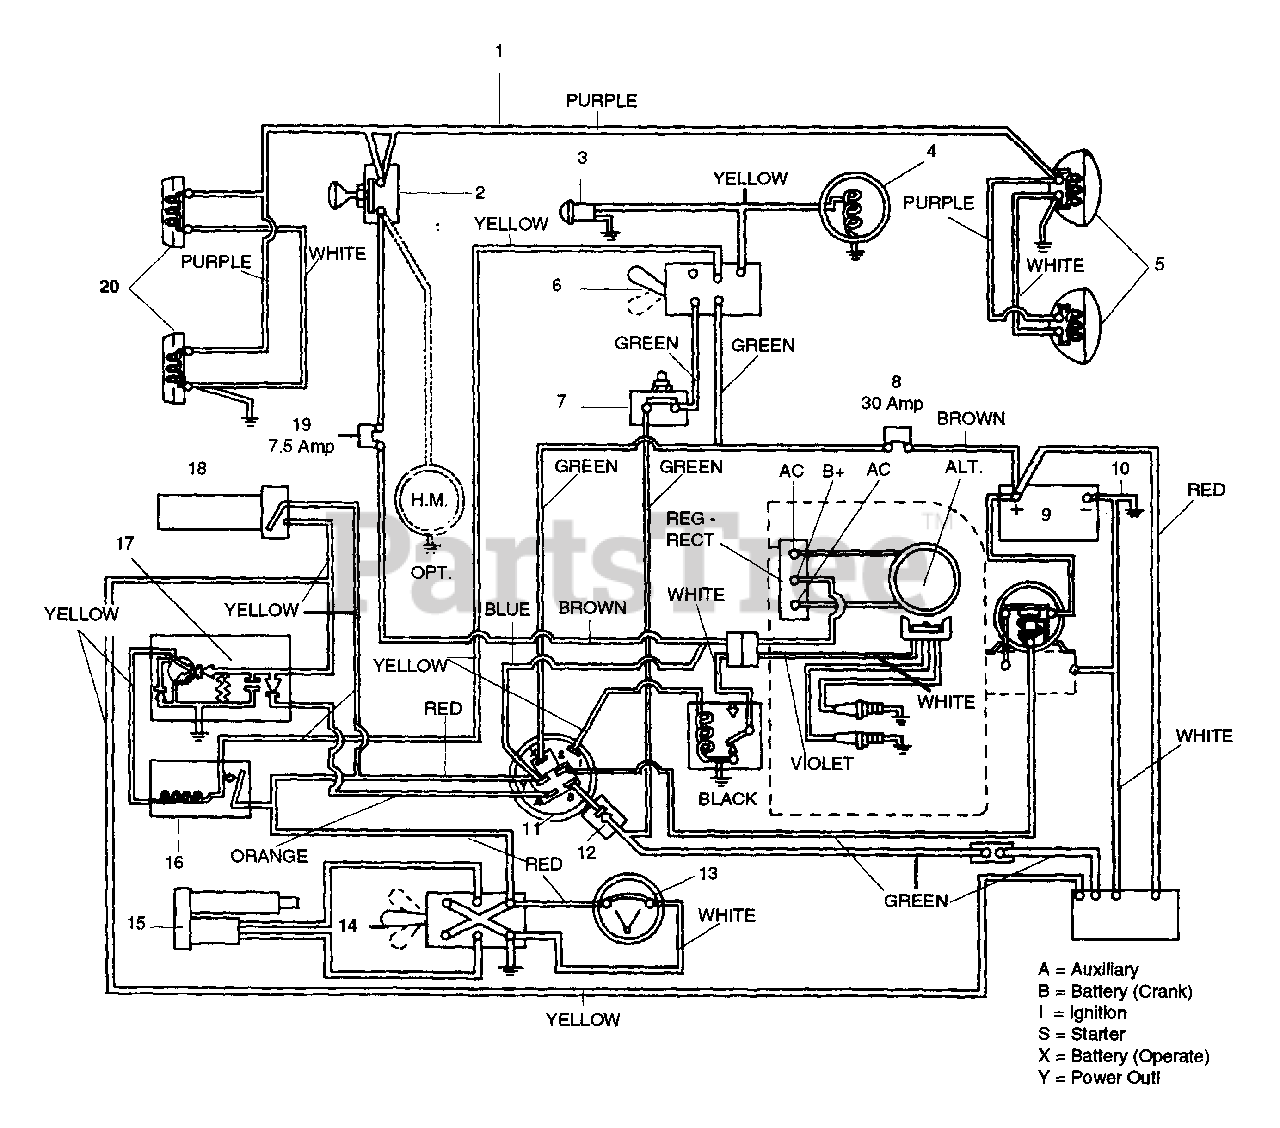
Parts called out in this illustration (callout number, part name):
1	WIRE HARNESS HT16 TW
1	WIRE HARNESS 18TW
2	LIGHT SWITCH ASSEMBLY
2	LIGHT SWITCH
3	PTO INDICATOR LIGHT
3	LAMP SOCKET
3	SPEED NUT
4	ELECTRIC CLUTCH
5	HEADLIGHT BULB, 1156
6	SWITCH ASSEMBLY
7	SAFETY SWITCH
8	30 Amp Fuse
9	BATTERY
10	GROUND CABLE .25X6.50X.31
11	SWITCH ASSEMBLY
12	DIODE ASSEMBLY
13	VOLTMETER
14	SWITCH ASSEMBLY
15	ACTUATOR
16	RELAY
17	TIME DELAY MODULE
18	SWITCH- DOUBLE POLE N.O./N.O.
19	7.5 Amp Fuse
